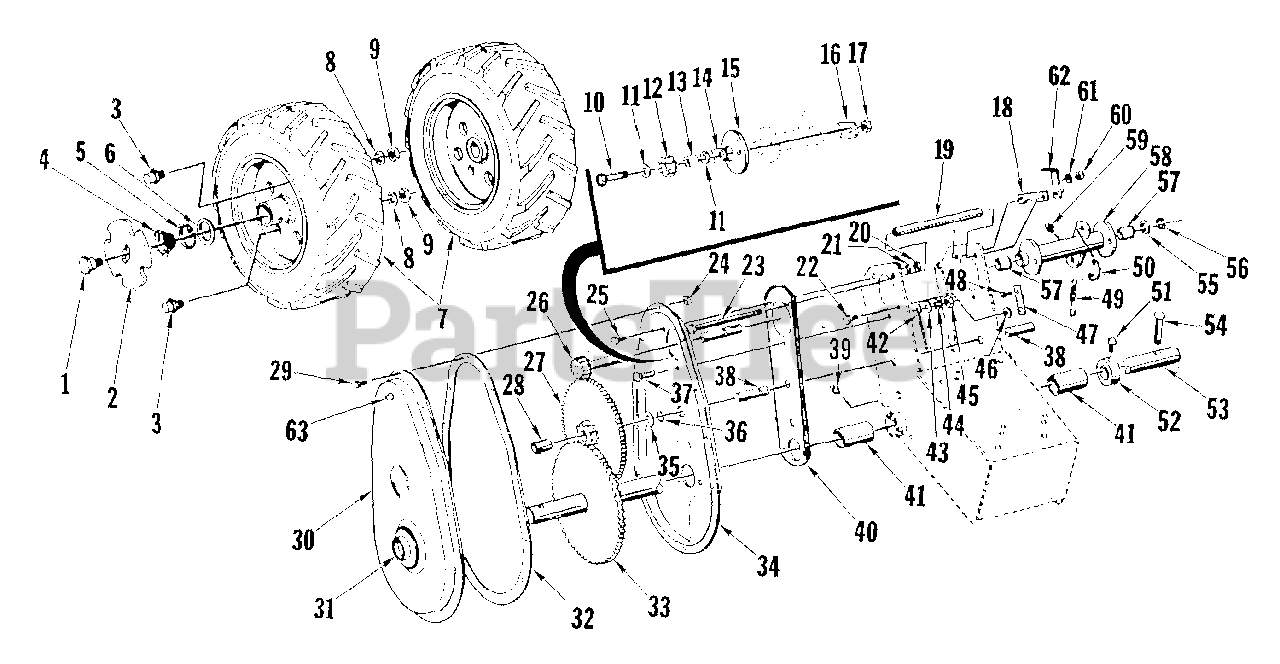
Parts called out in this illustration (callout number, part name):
1	BOLT, Shoulder
2	PLATE, Locking
5	RING, Retaining
7	WHEEL & TIRE ASSEMBLY
8	WASHER, Plain, 5/16"
9	NUT, Hex, 3/8-16
10	BOLT, Hex, Head, 3/8-16 x 1-1/2 (L.H.)
11	WASHER, Plain, 5/16"
12	PINION, Reverse
13	SPACER, Pinion
14	SPACER, Reverse Pinion
17	NUT, Hex, 3/8-16 (L.H.)
18	PLATE, Friction Stop
19	SPACER, Frame
20	NUT, Hex, 5/16
21	WASHER, Lock, 5/16"
22	SCREW, Hex, Head, 1/4-20 x 5/8
24	NUT, Hex, Tinnerman
25	SCREW, Hex Head, 5/16-18 x 5/8
26	SHAFT ASSEMBLY, Pulley
27	GEAR ASSEMBLY, Intermediate
28	BEARING, Intermediate Pin
29	SCREW, Self Tapping, #10 x 3/8
30	COVER ASSEMBLY, Gear Case
31	WASHER, Retaining
32	GASKET, Gear Case
33	AXLE & GEAR ASSEMBLY
36	RING, Retaining
37	SCREW, Hex Head, 3/8-16 x 1
38	SHAFT, Intermediate
39	FITTING, Grease
40	GASKET, Bearing Housing
43	WASHER, Plain, 3/8"
44	WASHER, Lock, 3/8"
45	NUT, Hex, 3/8
46	WASHER, Plain, 1/4"
47	DETENT, Neutral
48	SCREW, Self Tapping, #10 x 3/8
49	SPRING, Reverse Lever
50	EXTENSION, Spring
51	SCREW, Set, Square Head, 5/16-18 x 1/2
53	CLIP, Spring
56	RING, Retaining
57	BEARING, Bronze
58	HOUSING ASSEMBLY, Bearing
59	FITTING, Grease
60	NUT, Hex, 5/16-18
61	WASHER, Lock, 5/16"
62	GUIDE, Clutch Wire
63	FITTING, Grease
